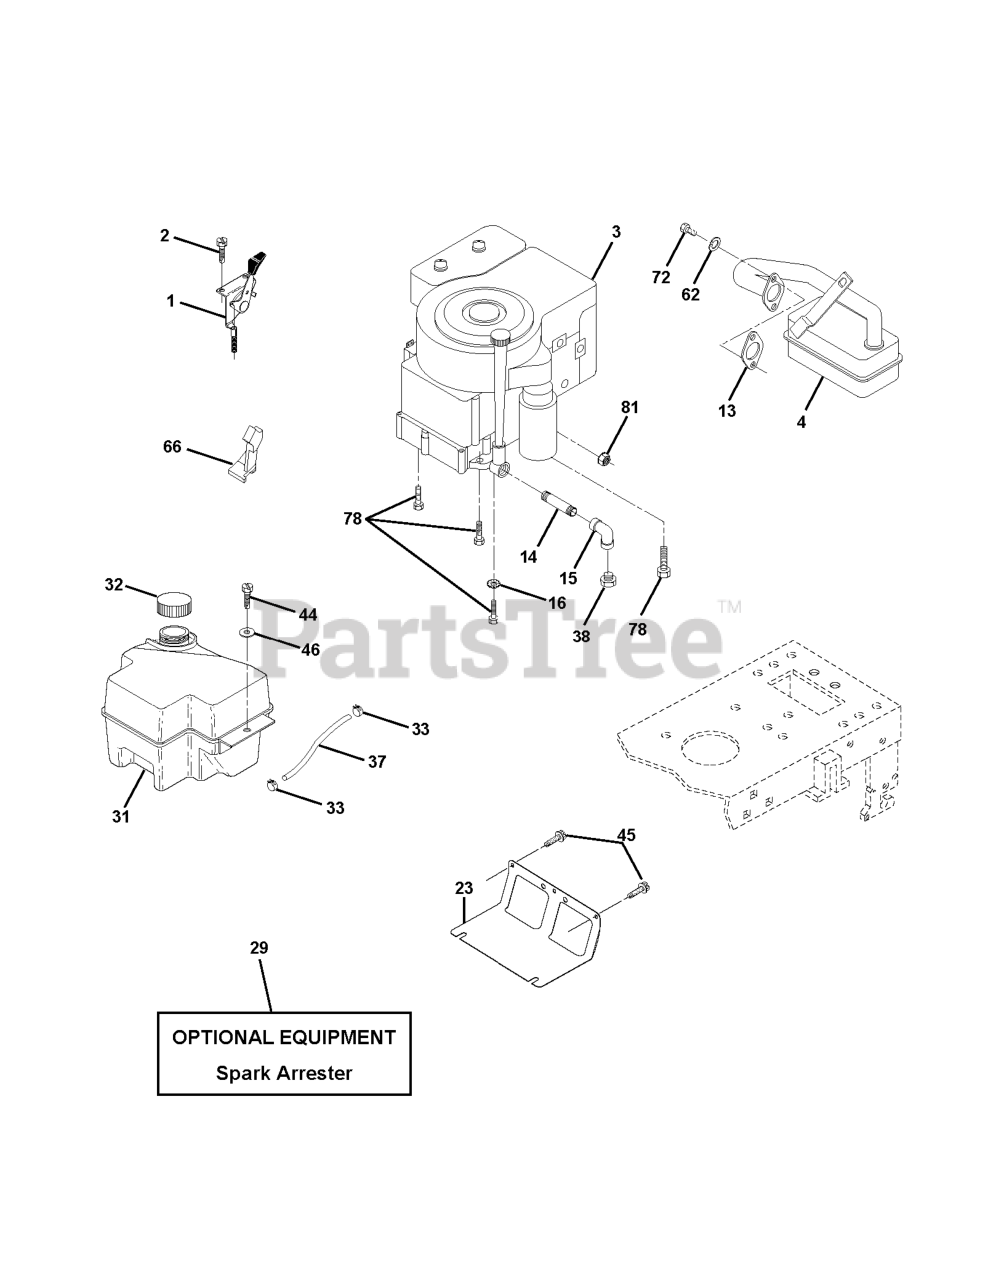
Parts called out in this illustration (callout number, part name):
1	CONTROL
2	SCREW LT
4	MUFFLER.LT.BRIGGS.14HP.IC/OHV
13	REPL BY 532 27 22-93
14	Nipple Pipe 3/8 Npt X 3-1/2
15	ELBOW
16	LOCKWASHER
23	SHIELD.BROWNING.DBR.GUARD
29	KIT.SPARK ARRESTOR 794945 B&S
31	FUEL TANK
32	FUEL CAP
33	HOSE CLAMP
37	LINE.FUEL.20
45	SCREW 3/8-16X3/4
62	WASHER.LOCK.HVY.HLCL.SPR.5/16
66	STOP THROTTLE
72	SCREW
78	SCREW.3/8-16
81	NUT FLANGE 1/4-20 STARTER NUT
